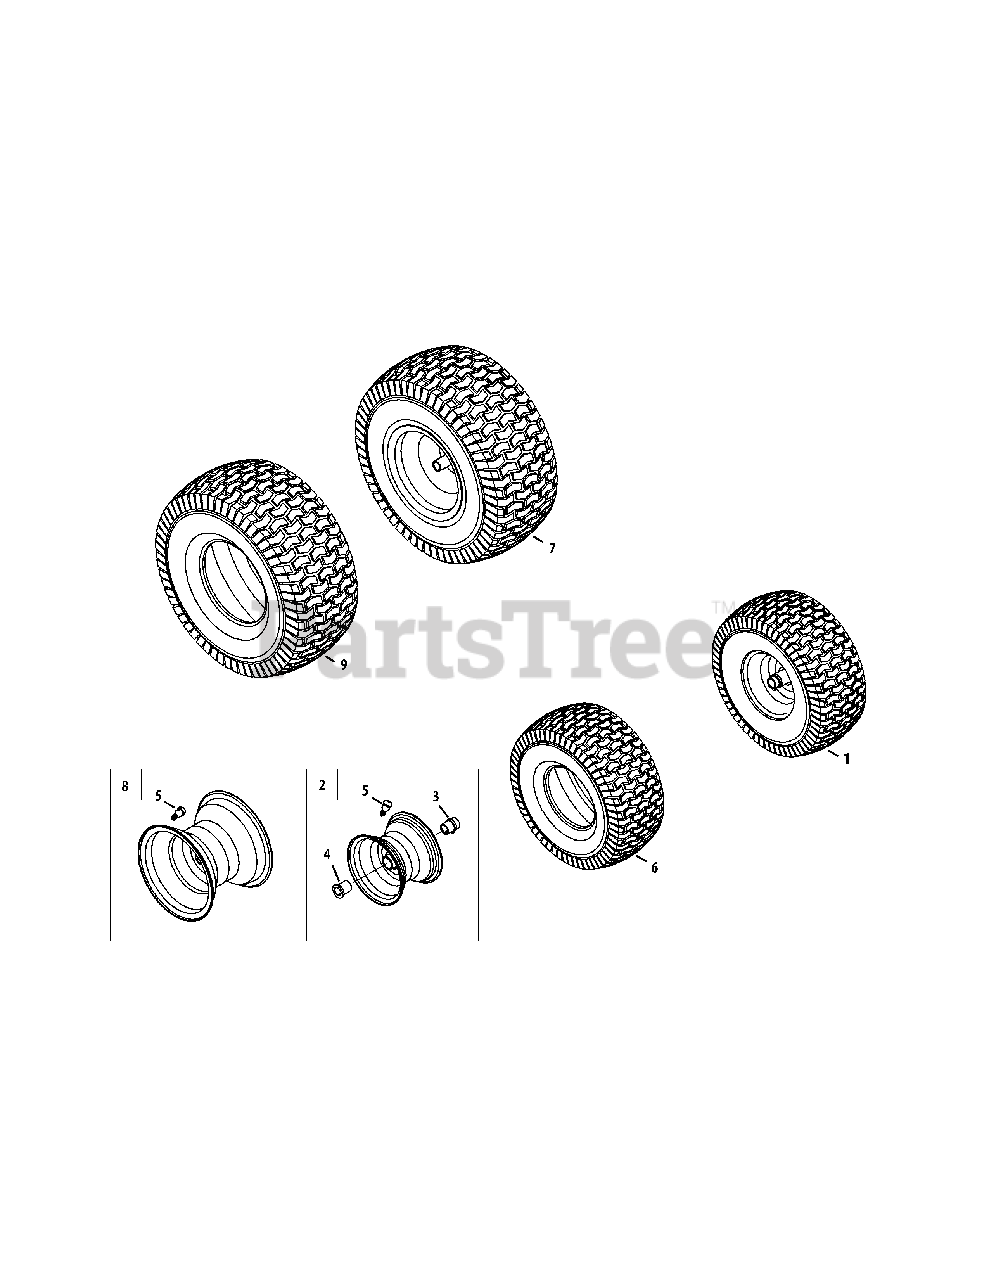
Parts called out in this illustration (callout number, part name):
1	Wheel Ass’y, Complete, 15 x 6 x 6
2	Rim Ass’y, 6.0 x 4.5, w/ Bearings
3	Bearing, Flange, .760 ID w/ Fitting
4	Bearing, Flange, .760 x 1.00 x 1.20
5	Valve, Tubeless Air
6	Tire, 15 x 6 x 6 Sq Shoulder
7	Wheel, Complete, 20 x 8 x 8
8	Rim, 8.0 x 7.0 x .750 ID
9	Tire, 20 x 8 x 8 Sq Shoulder
